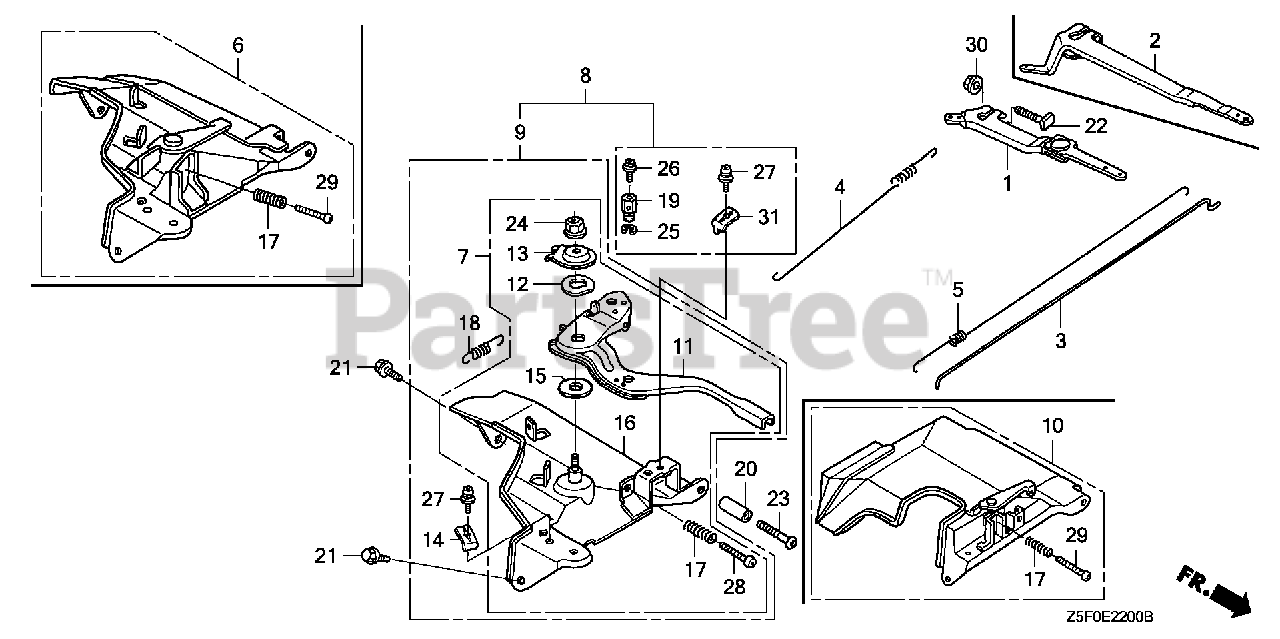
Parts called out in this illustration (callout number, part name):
2	ARM, GOVERNOR
3	ROD, GOVERNOR
4	SPRING, GOVERNOR (L=145.0MM) (WIRE DIAMETER 1.0MM)
5	SPRING, THROTTLE RETURN
9	CONTROL ASSY. (REMOTE)(COO)(FOR U.S.A.)
11	LEVER, CONTROL
12	SPRING, LEVER
13	WASHER, CONTROL LEVER
14	HOLDER, CABLE
15	SPACER, CONTROL LEVER
16	BASE, CONTROL
17	SPRING, CONTROL ADJUSTING
18	SPRING, CABLE RETURN
21	BOLT, FLANGE (6X12) (CT200)
22	BOLT, GOVERNOR ARM
24	NUT, SELF-LOCK (6MM)
27	SCREW, PAN (5X16)
28	SCREW, PAN (5X28)
30	NUT, FLANGE (6MM)
